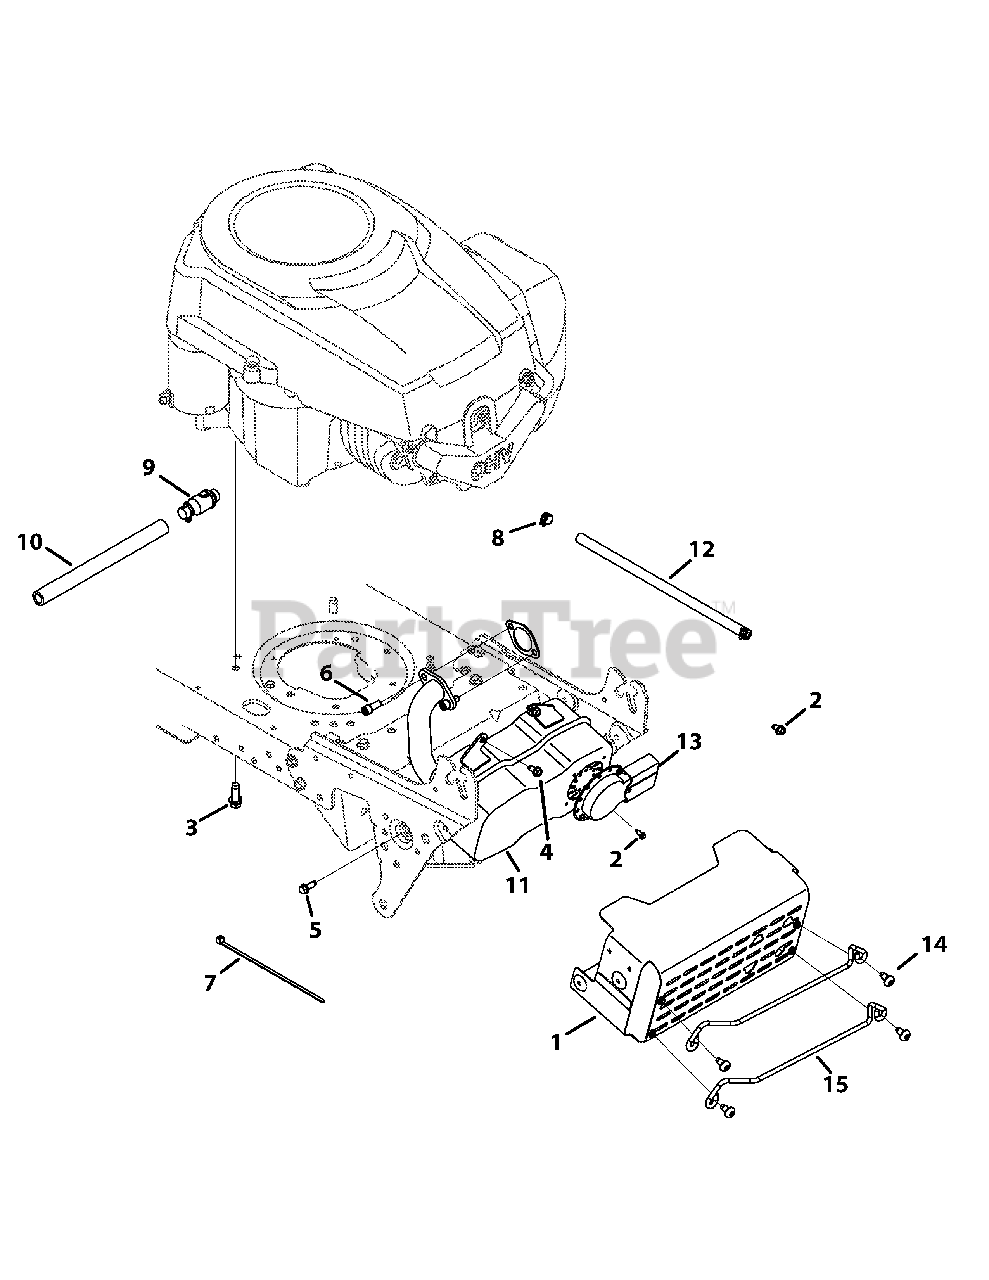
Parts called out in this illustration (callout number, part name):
1	Muffler Shield Assembly
2	Screw, 8-18 x .500
3	Screw, 3/8-16 x 1.0
4	Screw, 1/4-20 x .500
5	Screw, 1/4-20 x .750
6	Socket Screw, 5/16-18 x .750
7	Cable Tie
8	Clamp Hose, .490 diameter
9	Oil Drain
10	Oil Drain, Extension Hose
11	Muffler
12	Fuel Hose, Low Permeation
13	Muffler Deflector Long
14	Pan Torx Screw 1/4
15	Muffler Guard Rod
